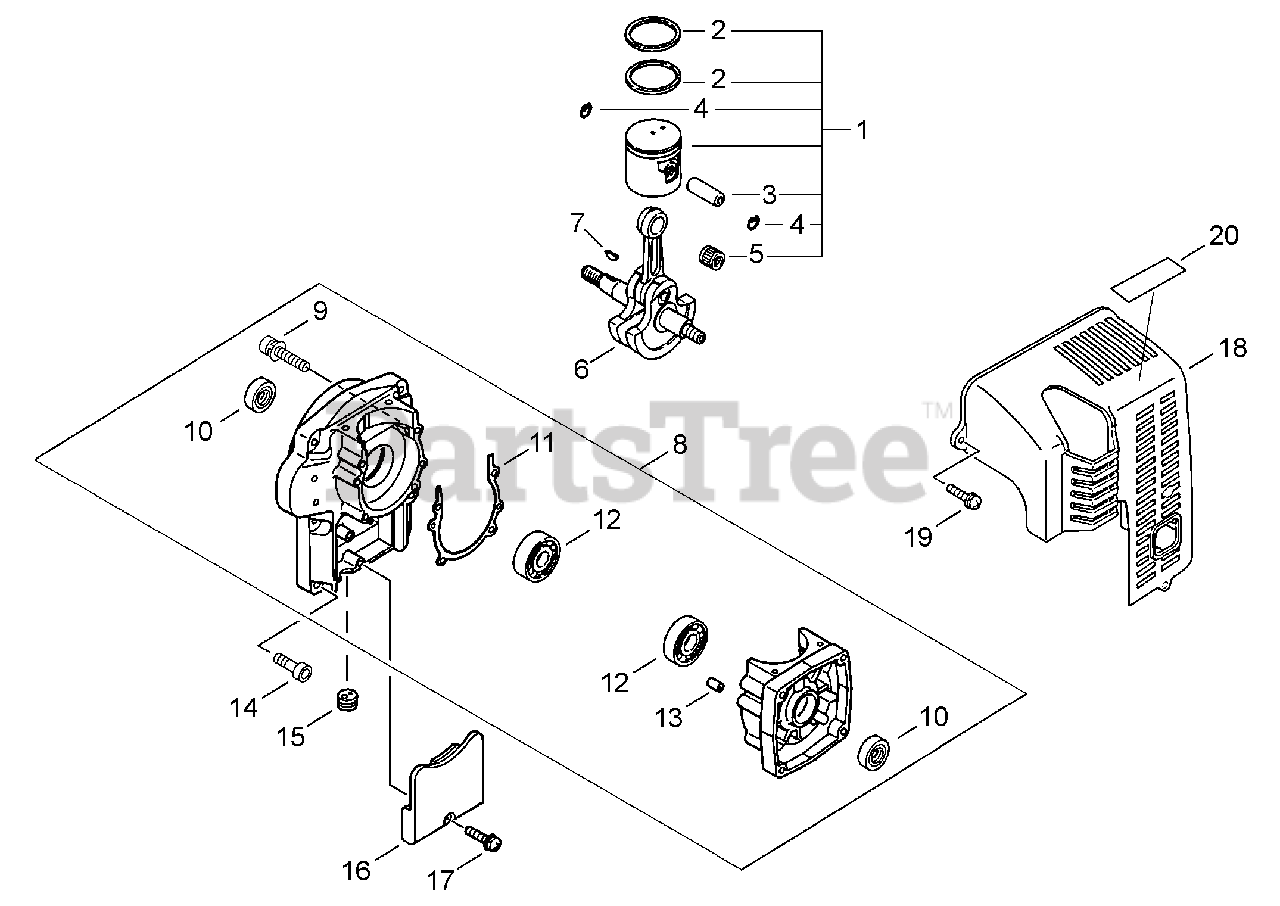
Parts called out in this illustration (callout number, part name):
1	PISTON KIT
2	RING, PISTON
3	PIN, PISTON
4	RING, RETAINING - 8
5	BEARING, NEEDLE
6	CRANKSHAFT ASSY
7	KEY - 3X14
8	CRANKCASE KIT
9	SCREW - 5X40
10	SEAL, OIL
11	GASKET, CRANKCASE
12	BEARING, BALL - 6202
13	PIN - LOCATING
14	SCREW - 5X25
16	COVER, DUST
17	SCREW - 5X18
18	COVER, ENGINE
19	SCREW - 5X20
20	LABEL - HOT SURFACE
